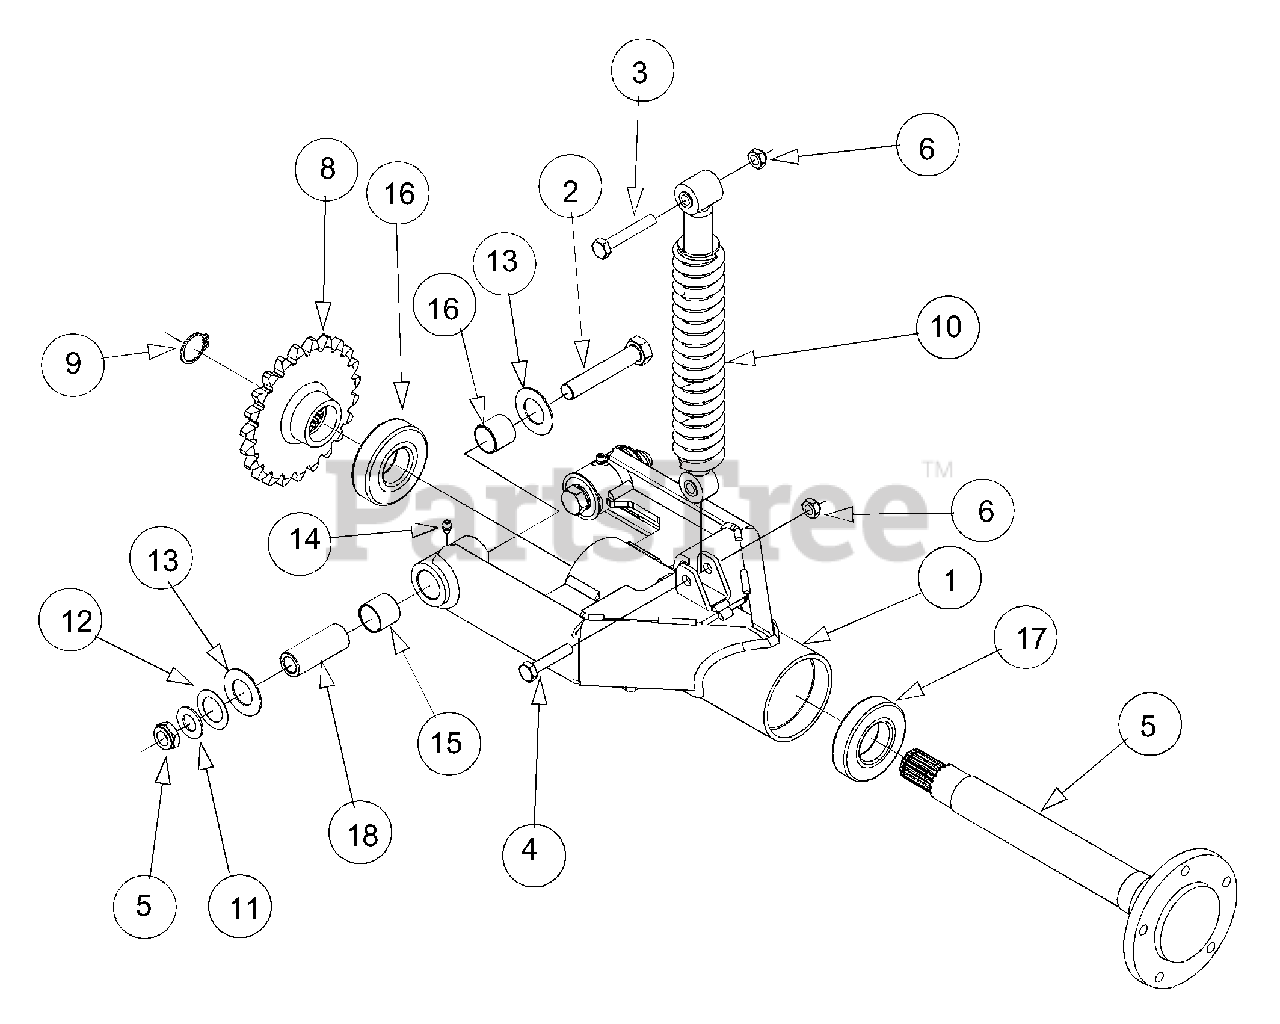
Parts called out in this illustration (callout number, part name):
3	Screw, M10-1.25 x .65, Gr8
4	Screw, M10-1.25 x .50, Gr8
5	Axle Shaft, Rear Drive
6	Nut, Nylon Lock, M10 x 1.25
7	Jam Nut, Nylon Lock, 5/8-18
9	Retaining Ring, External, 1.14
10	Shock Absorber, 2.9Stroke
11	Washer, Flat, .65 x 1.25 x .075
12	Washer, Flat, 1.06 x 1.56 x .020
13	Washer, Flat, 1.010 x 1.86 x .060
14	Lube Fitting, 3/16
15	Bearing Flange, 1.0 x 1.125 x 1.0
16	Ball Bearing, Internal Axle
17	Ball Bearing, External Axle
18	Spacer, .63 x 1.0 x 2.594
